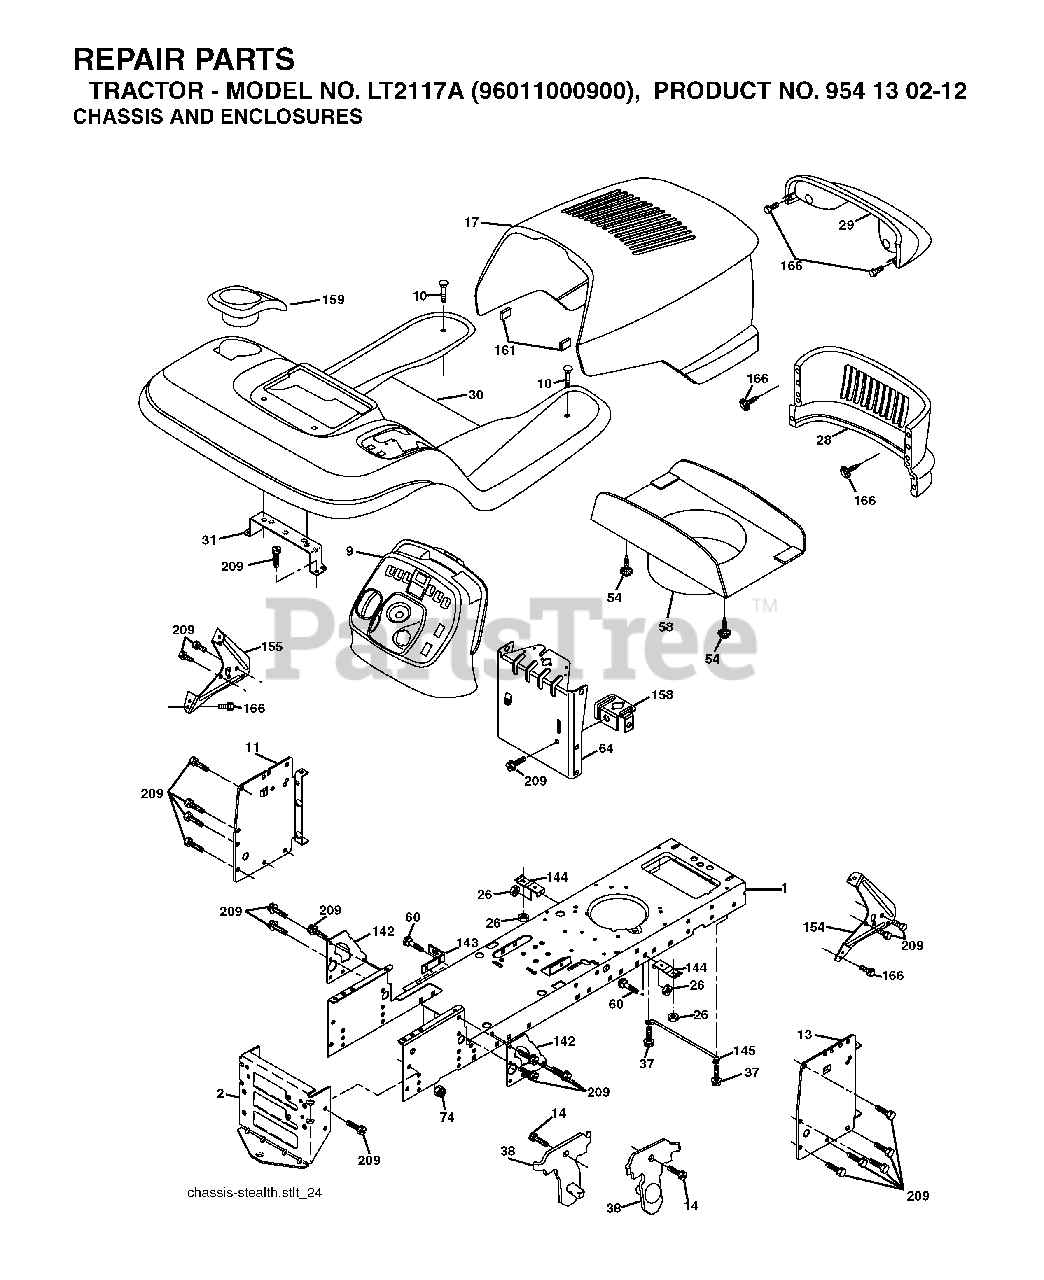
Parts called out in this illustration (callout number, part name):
1	CHASSIS STAMPING
2	DRAWBAR, 12GA
10	BOLT D
13	PANEL DASH RH
14	SCREW LT
26	NUT
37	SCREW LT
38	BRACKET.ASM.PIVOT.MOWER.REAR
58	DUCT HOOD
64	DASH LOWER
74	LOCKNUT
142	PLATE REINFORCEMENT
143	BRACKET, SWAYBAR CHASSIS
144	BRKT, FOOT REST
145	ROD PIVOT CHASSIS/HOOD
161	EXTRUSION BUMPER
166	SCREW
206	SHOULDER BOLT 5/16-18TT
209	SCREW, 3/8-16X3/4
